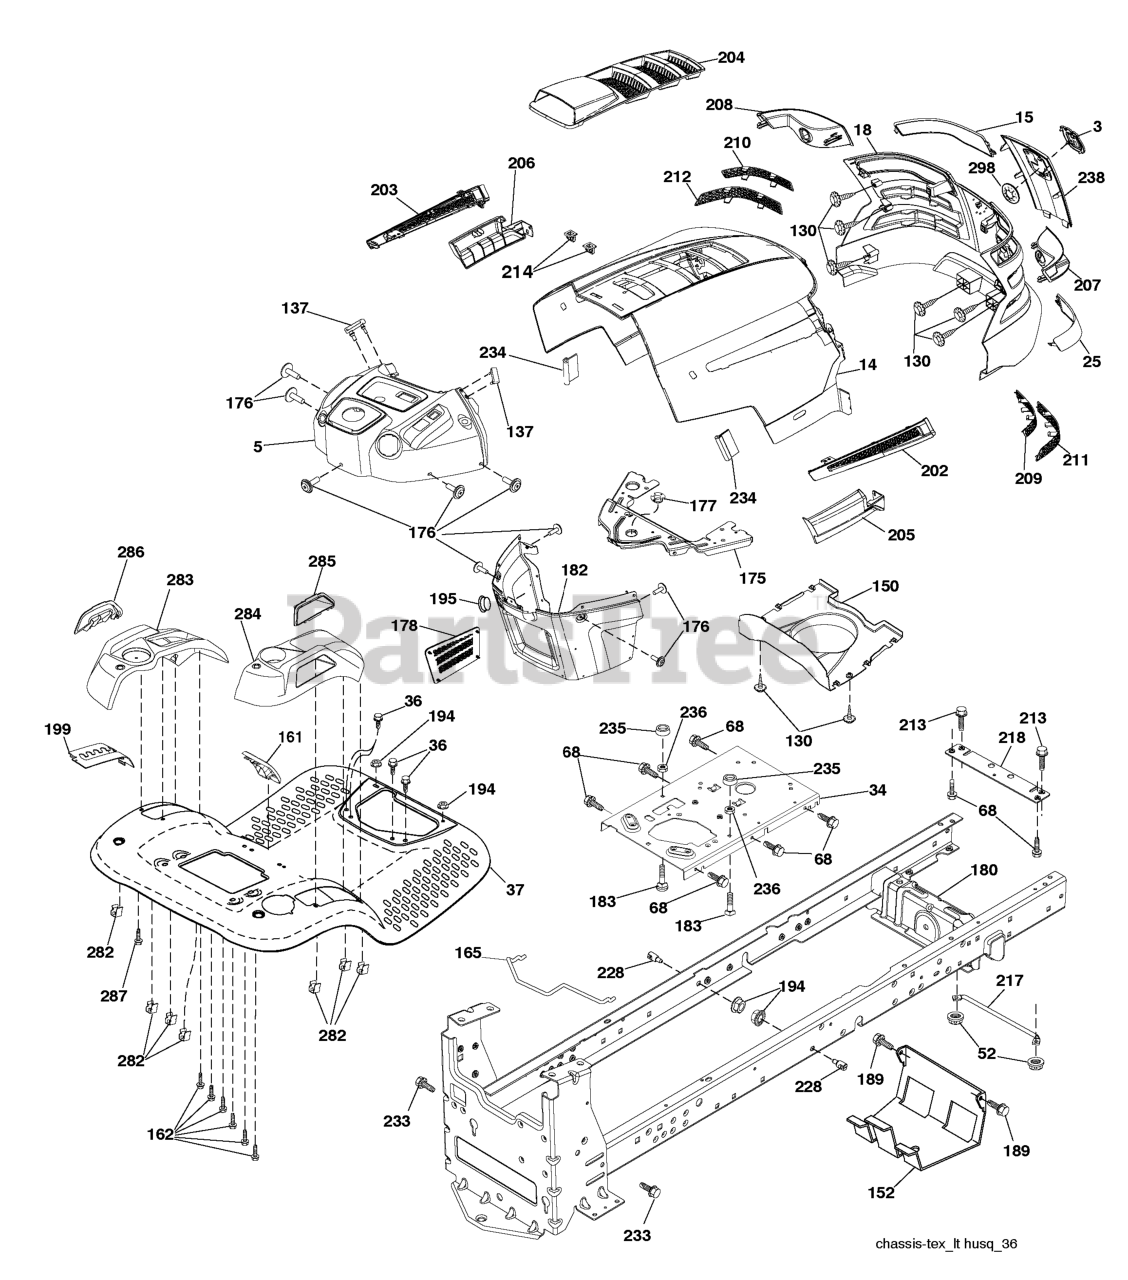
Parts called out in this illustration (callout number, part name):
3	RP LOGO
5	DASH.ASM.HUSQ.GT
14	HOOD
15	LENS.LH.TEX.GT.HUSQ.CL
18	GRILL.ASM.HUSQ.TG/CRD.W/TRIM
25	LENS.RH.TEX.GT.HUSQ.CL
34	PLATE.ENGINE.WELDED.CHASSIS
36	SCREW 5/16"
37	FENDER.TLT.FS.W/CPH/FW/RSF.ORN
52	LOCKNUT
68	Screw 5/16-18 x 1/2
130	SCREW.#10 X 0.750.BOS
137	BUMPER DASH
150	AIR.DUCT.HOOD.TEX.GT.HUSQ
152	SHIELD.BROWNING.W/TEX
161	WINDOW FUEL
162	SCREW.HI-LO.CONSOLE
165	SUPPORT.TANK.REAR.W/TEX
175	PLATE.CROSSMEMBER.HUSQ
176	SCREW.#10-24X5/8.RN.QU
177	BUSHING, STEERING
178	CARGO.ASM.NET.TXGT.W/C
180	CHASSIS
181	BUSHING.MNT.FEND.CRGO.
182	DASH.LOWER.COMMON.12V.ADAPTOR
183	BOLT.5/16-18X1-1/4 FULL.THREAD
189	SCREW
194	NUT LOCK HEX FLANGE 5/16-18
195	PLUG.HOLE.DASH.LOWER.12V.BLK
199	PLATE.DECK.LIFT.HUSQ.LT
202	VENT.SIDE.HOOD.HUSQ.RH.GREY
203	VENT.SIDE.HOOD.HUSQ.LH.GRAY
204	HOOD VENT
205	SKIRT.HOOD.SIDE.HUSQ.RH.GREY
206	SKIRT.HOOD.SIDE.HUSQ.LH.GREY
207	BEZEL.RH.TEX.GT.HUSQ
208	BEZEL.LH.TEX.GT.HUSQ
209	INSERT.HEX.GRILL.HUSQ.GREY
210	INSERT.HEX.GRILL.HUSQ.
211	INSERT.HEX.GRILL.HUSQ.
212	INSERT.HEX.GRILL.HUSQ.
213	BOLT
214	CLIP.RETAINER.TINNER.
217	ROD.PIVOT.HOOD
218	X-PIECE.HOOD.STOP.NON/
228	STUD.FASTNER.W/ANTI-ROTATE
233	BOLT.SHOULDER
234	BUMPER.HOOD.TEX.HUSQVARNA
235	SPACER FENDER
236	NUT.CENTERLOCK.5/16-
238	TRIM.HUSQ.TG/CRD.SERVICE
282	CLIP.RETAINER.CONSOLE.LT.HUSQ
283	CONSOLE.DECK.LFT.R.SDFL.HUSQLT
284	CONSOLE.CNTRL.
285	CONSOLE INSERT RH
286	CONSOLE.INSRT.LH.HUSQ.LT.BLACK
287	SCREW 1/4X20
